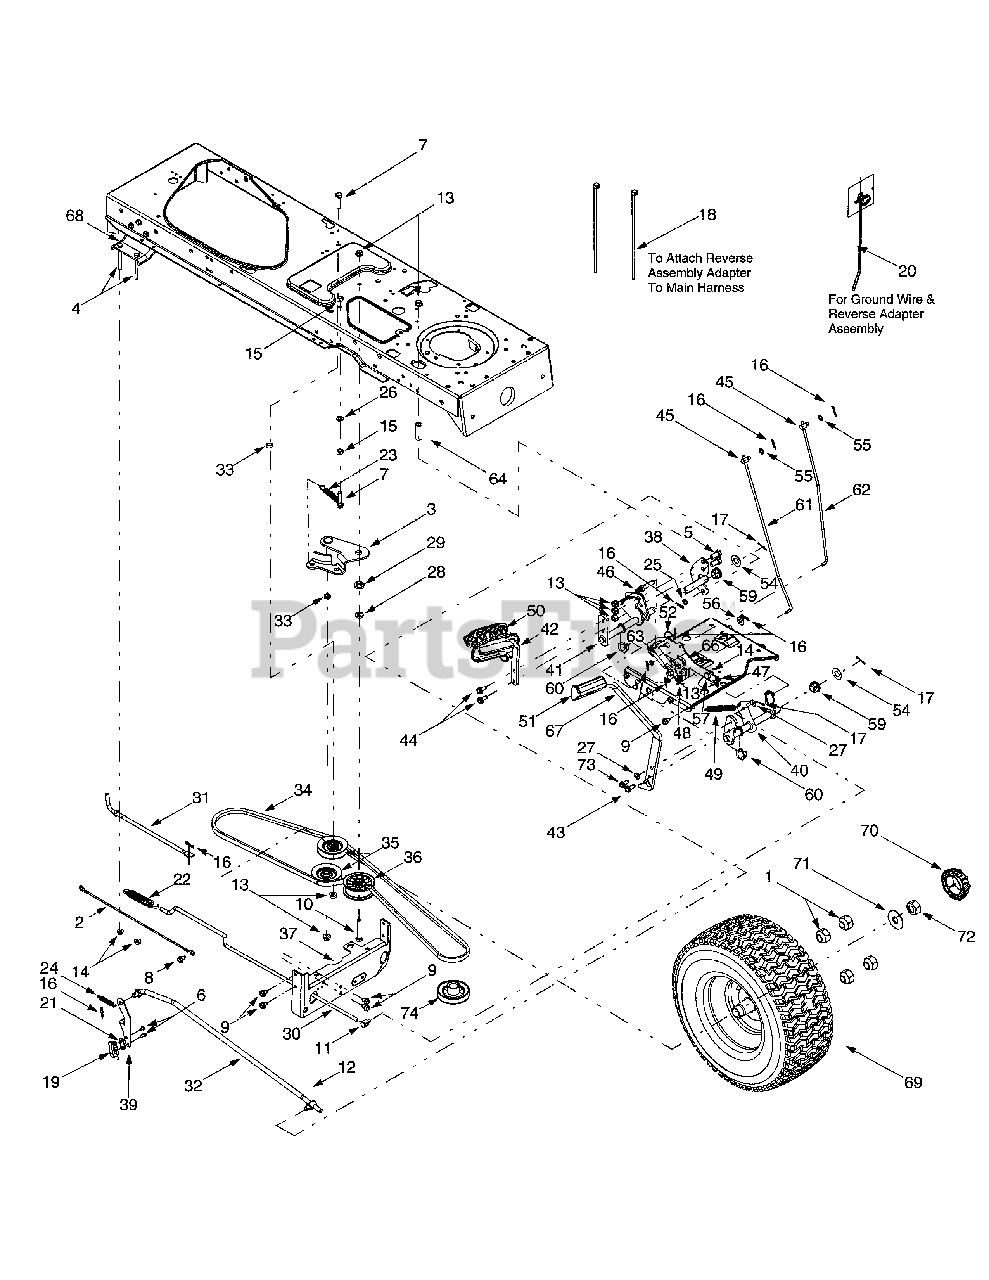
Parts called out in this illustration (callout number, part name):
1	Lug Nut, 3/4-16
2	Reverse/Ground Wire Harness Adapter
3	Double Idler Bracket Assembly
4	Hex Cap Screw, 5/16-18 x 2.75
5	Hex Cap Screw, 3/8-16 x .75
6	Screw, #8-18 x .5
7	Hex Cap Screw, 3/8-16 x 1.5
8	Self-tapping Screw, 1/4-20 x .50
9	Self-tapping Screw, 5/16-18 x .625
10	Hex Cap Screw, 3/8-16 x 2.25
11	Ferrule, 5/16-18
12	Ferrule, 3/8-24
13	Flange Lock Nut, 3/8-16
14	Flange Lock Nut, 5/16-18
15	Hex Nut, 3/8-16
16	Internal Cotter Pin
19	Short Spring Switch
20	Push-mount Cable Tie
21	Insulator Nut Plate
22	Extension Spring, .59 x 4.0
23	Extension Spring, .5 x 3.97
24	Extension Spring, 3/8 x 1.44
25	Flat Washer, .385 x .62 x .063
26	Lock Washer, 3/8
27	Flat Washer, .344 x .750 x .120
28	Flat Washer, .407 x .812 x .135
29	Shoulder Spacer, .38
30	Hydrostatic Control Rod
31	Hydrostatic Bypass Rod
32	Hydrostatic Brake Rod
33	Spacer, .376 x .625 x .22
34	Drive Belt
35	V-idler Pulley, 3.06
36	Flat Idler Pulley, 2.75
42	Hydro Pedal Assembly
43	Self-tapping Screw, 5/16-18 x .875
44	Self-tapping Screw, 5/16-18 x .75
45	Ferrule, 1/4-20
46	Pin, 3/8-16 x 2.43
47	Compression Spring, .40 OD x 1.17
48	Extension Spring, .50 OD x 1.41
49	Extension Spring, .50 OD x 6.37
50	Drive Pedal Pad
51	Brake Pedal Pad
52	Flat Washer, .411 x 1.25 x 1.0
54	Flat Washer, .64 x 1.24 x .06
55	Flat Washer, .344 x .062 x .03
56	Flat Washer, .406 x .875 x .105
57	Shoulder Screw, .437 x 1.62
59	Hex Flange Bearing
60	Split Hex Flange Bearing
61	Cruise Control Rod
62	Brake Lock Control Rod
63	Cruise Latch
64	Spacer, 5/16 x 1.54
66	Drive Lockout Bracket
70	Hub Cap
71	Flat Washer, .780 x 1.59 x .062
72	Jam Nut, 3/4-16
73	Self-tapping Screw, 5/16-18 x .75
74	Engine Pulley
